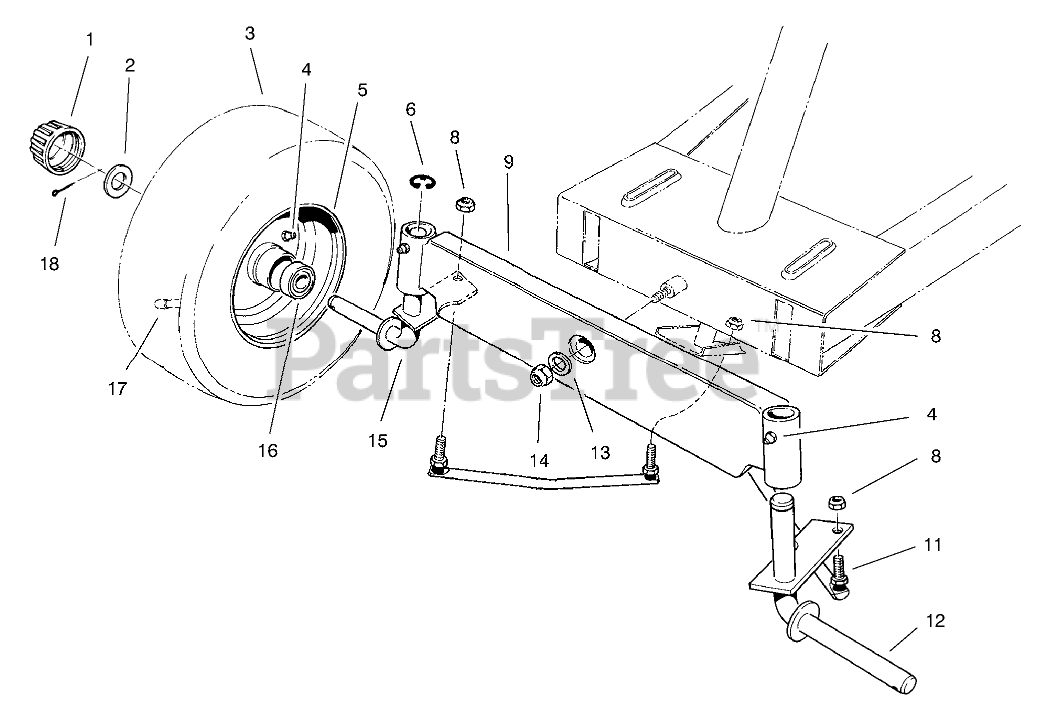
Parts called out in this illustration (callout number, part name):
1	CAP-HUB
2	WASHER-PLAIN
3	TIRE,PNEU.11X4.00X5
4	FITTING-GREASE
6	E-RING
8	NUT-LOCK
11	TIE ROD ASM
12	WHEEL SPDLE WA LH (RED)
13	WASHER-FLAT
14	NUT-LOCK, NI
15	WHEEL SPDLE WA RH (RED)
16	BEARING-WHEEL
17	STEM-VALVE
18	PIN-COTTER
